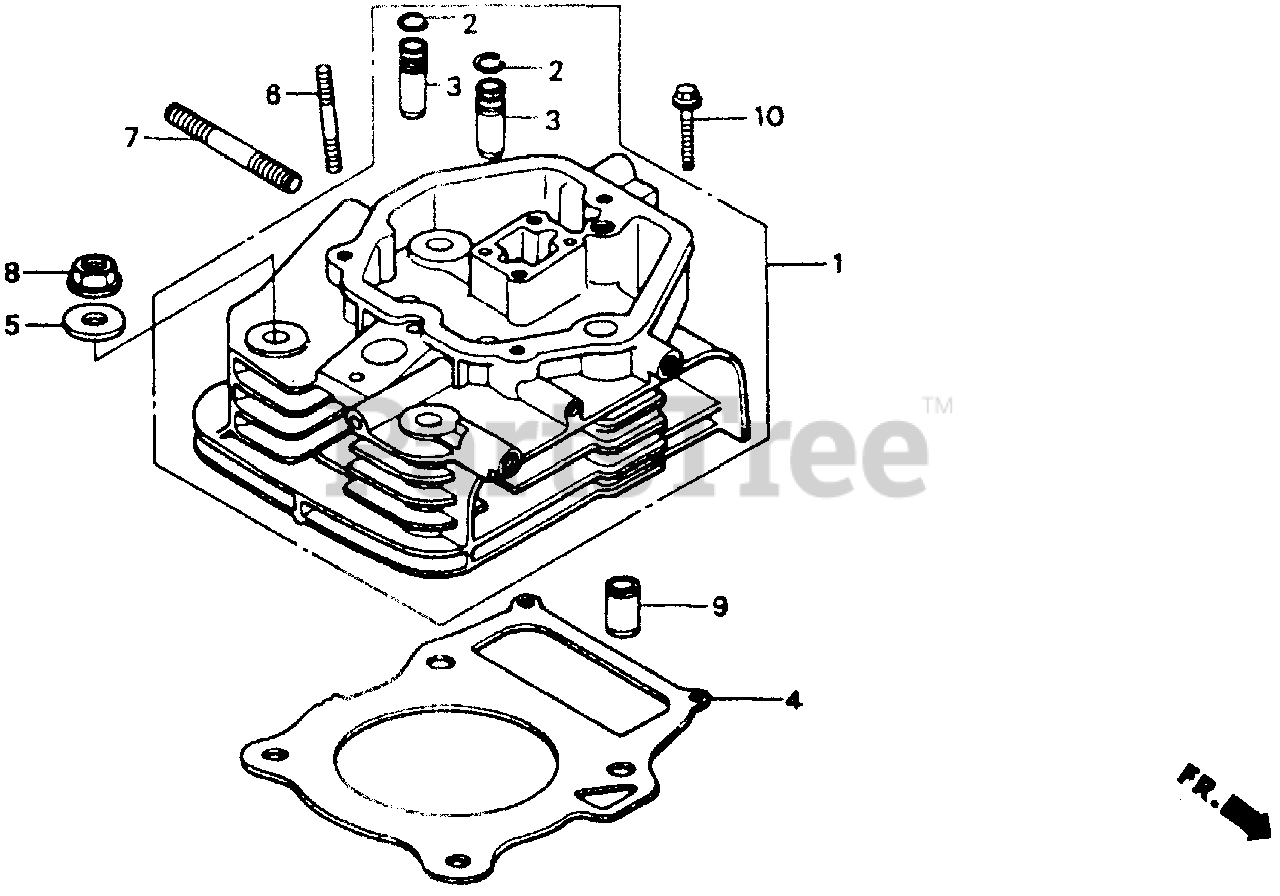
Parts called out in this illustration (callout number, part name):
1	CYLINDER HEAD
2	CLIP, VALVE GUIDE
3	GUIDE, VALVE (OS)
4	GASKET, CYLINDER HEAD (1.1) (A)
4	GASKET, CYLINDER HEAD (1.2) (B)
4	GASKET, CYLINDER HEAD (1.3) (C)
5	WASHER (10MM)
6	BOLT, STUD (6X32)
7	BOLT, STUD (8X28)
8	NUT, FLANGE (10MM)
9	PIN A, DOWEL (12X20)
10	BOLT, FLANGE (6X28)
